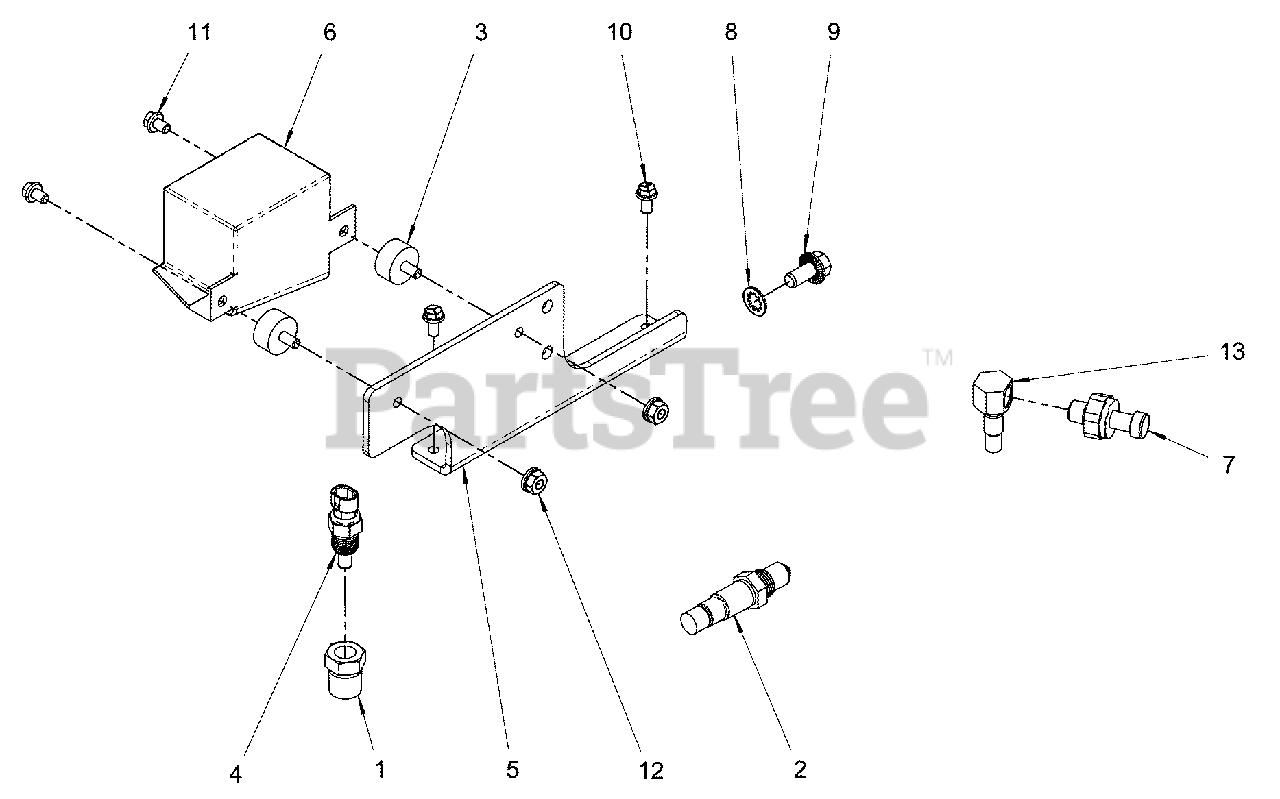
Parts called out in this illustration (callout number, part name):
1	* BUSHING
3	* RELAY BOX ISOLATOR
4	OIL PRESSURE SENSOR
5	* BRACKET
6	MAIN ENGINE HARNESS
7	OIL PRESSURE SENDER
8	* WASHER
9	* BOLT
10	* BOLT
11	* BOLT
12	* NUT
13	FITTING
